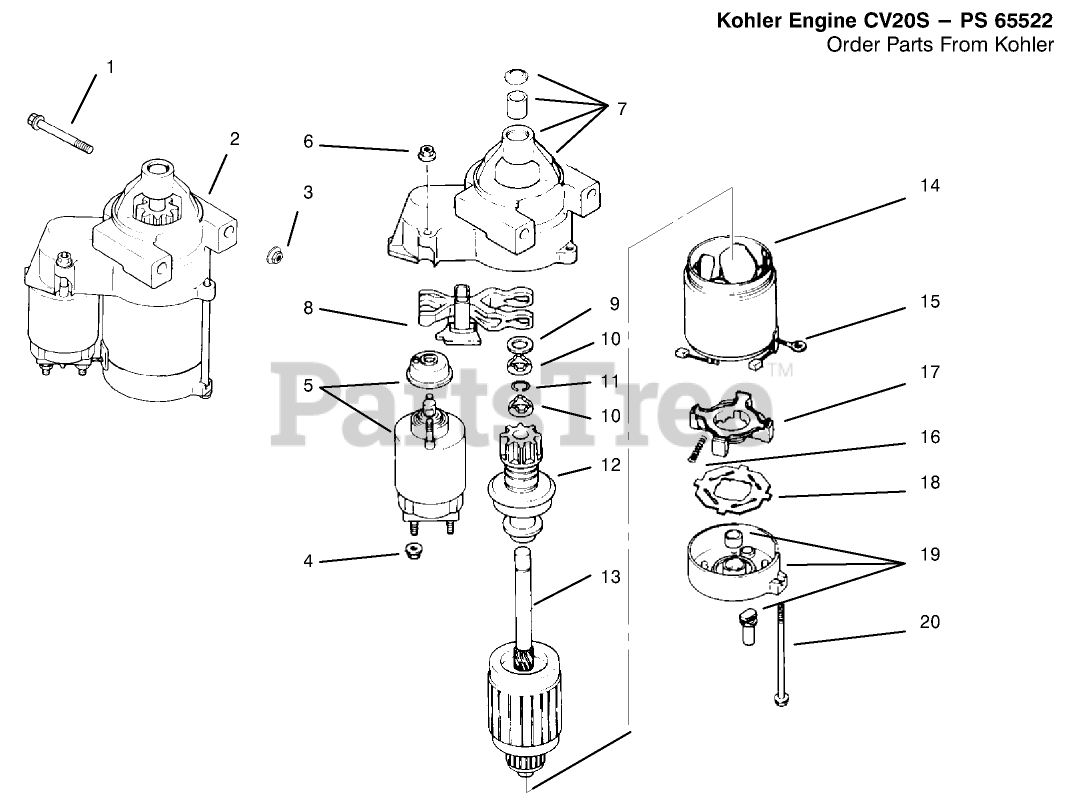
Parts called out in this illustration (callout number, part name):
1	Scew
2	Starter Solenoid Shift (Incl. Ref. #4-20)
3	Nut
4	Nut
5	Cap Drive End
6	Nut
7	Solenoid
8	Lever Starter Drive
9	Washer
10	Nut
11	Ring-Retainer
12	Drive Pinion
13	Armature
14	Frame
15	Kit-Brush (Incl. Ref. #16)
16	Spring Brush
17	Holder-Brush
18	Insulator
19	Cap-Commutator End
20	Bolt
